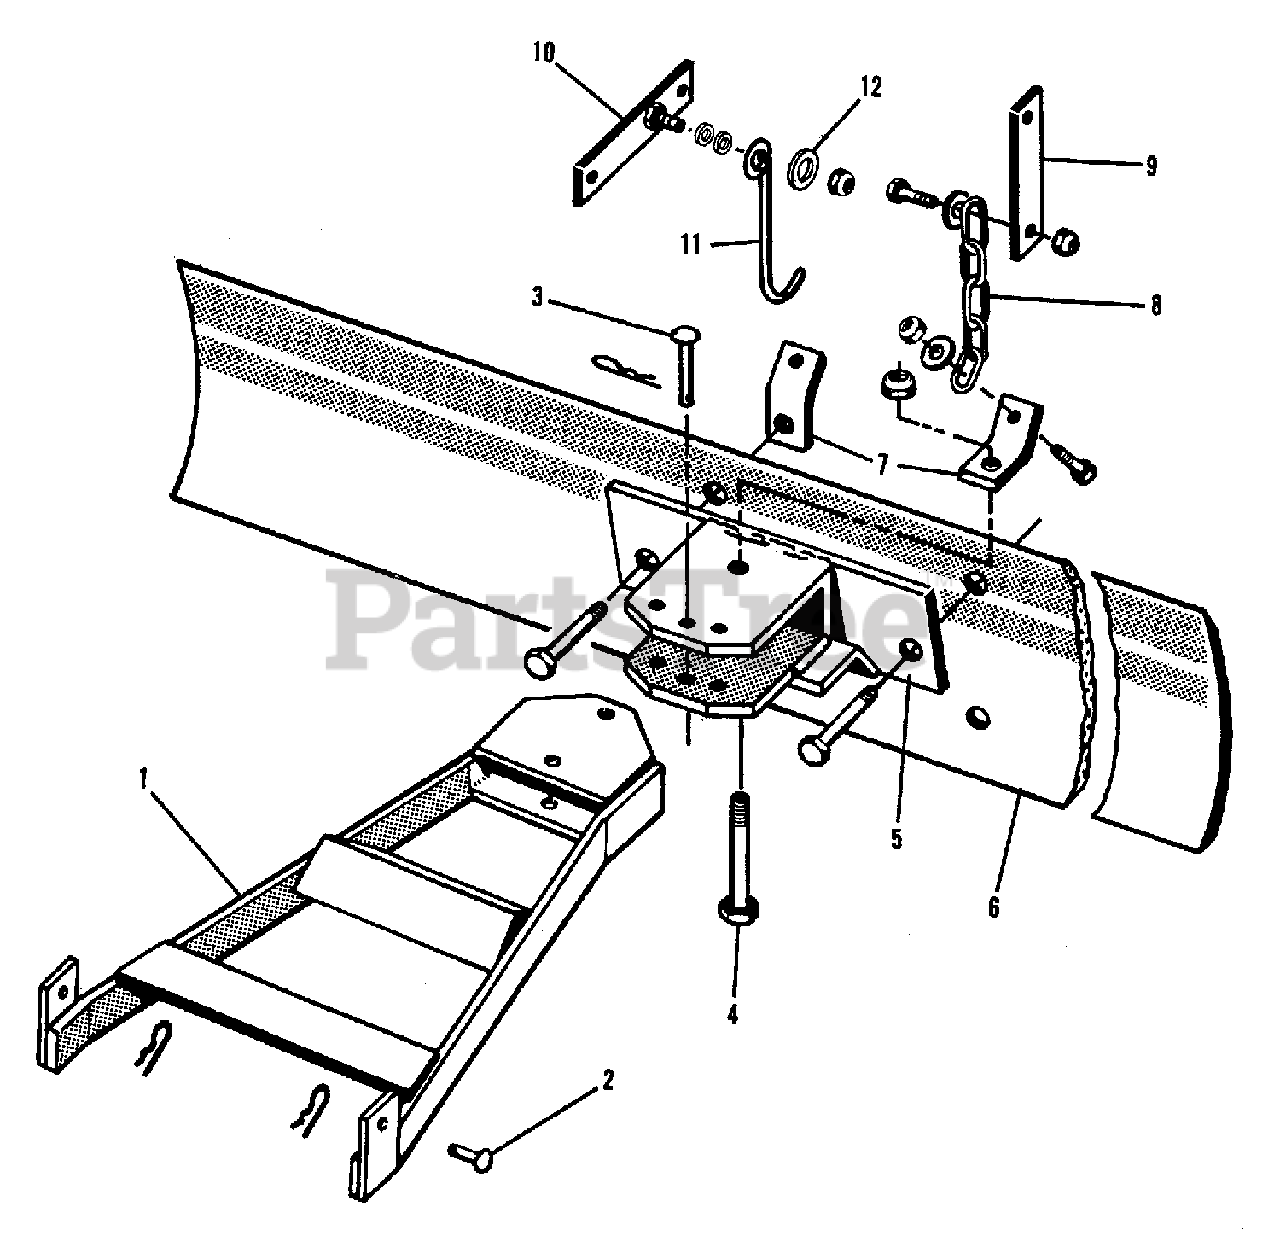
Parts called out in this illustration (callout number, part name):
1	DRAWBAR ASSEMBLY, Grader
2	PIN, Round Head
2	PIN, Quick
3	PIN, King
3	PIN, Quick
4	CAPSCREW, 5/8NC x 3
4	NUT, 5/8NC, Lock
5	HITCH ASSEMBLY, Grader
5	CAPSCREW, 5/8NC x 2
5	LOCKWASHER, 5/8
5	NUT, 5/8NC
6	BLADE, 42" Grader
7	LINK, Lift
8	CHAIN ASSEMBLY, Lift
8	CAPSCREW, 3/8NC x 1
8	WASHER, 3/8, Plain
8	NUT, 3/8NC, Lock
9	BRACKET, Lift
10	BRACKET ASSEMBLY, Transport
10	CAPSCREW, 5/16NC x 3/4
10	NUT, 5/16NC
10	LOCKWASHER, 5/16
10	WASHER, 5/16, Plain
10	NUT, 5/16NC, Lock
11	HOOK, Transport
12	WASHER, Special Nylon
